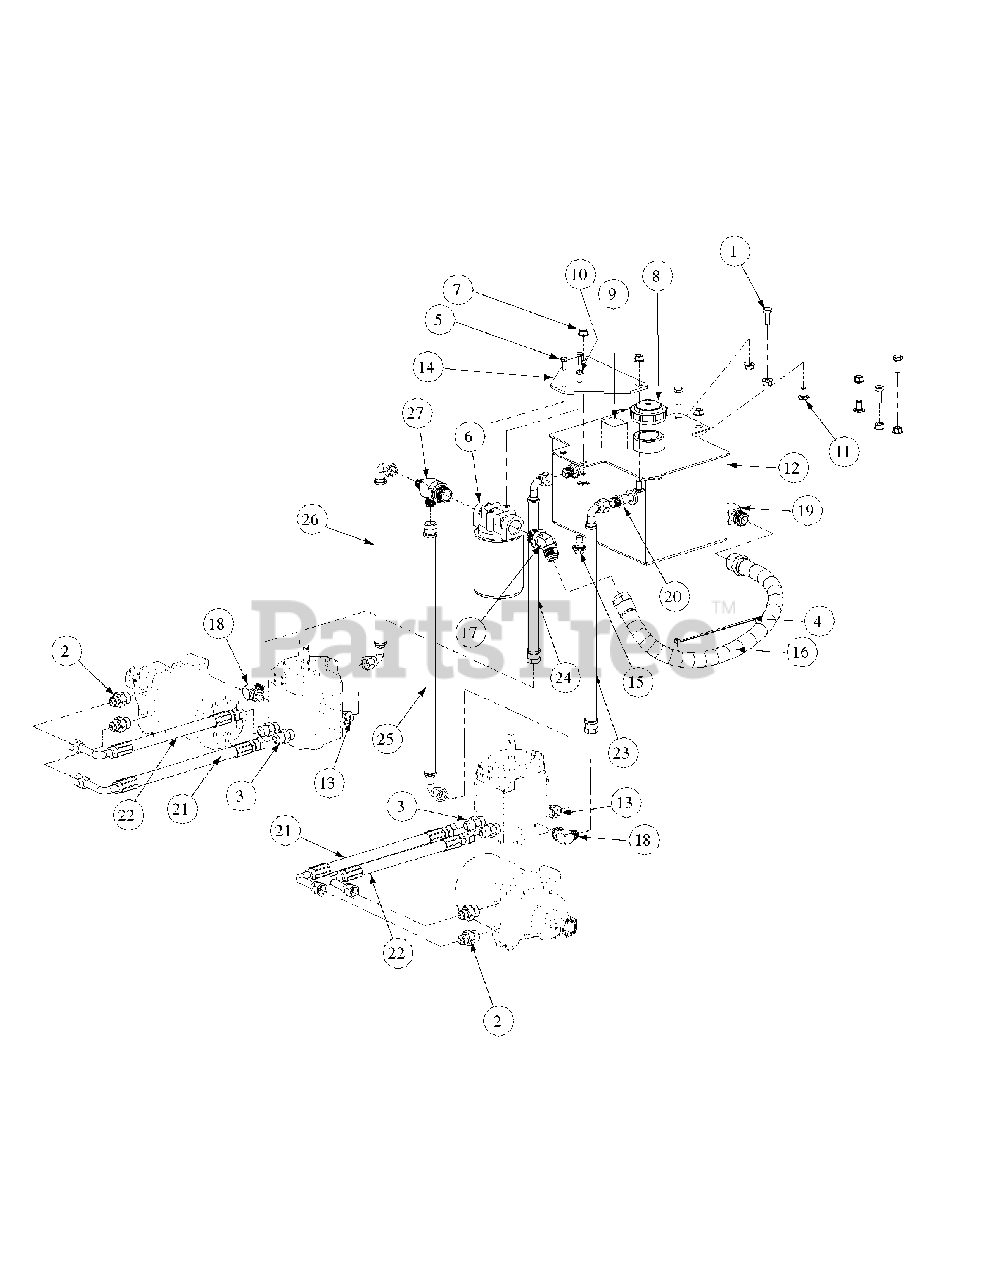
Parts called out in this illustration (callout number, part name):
1	Hex Cap Screw, 3/8-16, 1
2	Fitting 1/2 x 3/4 - O Ring
3	Fitting 1/2 x 3/4 - O Ring to Flare
4	Cable Tie, 3/16 x .05 x 7.4
5	Hex Cap Screw, 1/4-20, .75
6	Filter Head 3/4
7	Hex Nut Flange Lock, 3/8-16
8	Cap, Hydro Oil Tank
9	Decal Oil Only 20W50
10	Lock Washer, 1/4
11	Carriage Bolt, 3/8-16 x .75 LG.
12	Hydraulic Tank Assembly
13	Fitting Connector, 1/2 x 3/8
14	Oil Filter Mounting Plate
15	Oil Pan Drain w/ Seal and Plug
16	Tank to Filter Hose Assembly
17	Connector, 3/4 x3/4
18	Elbow Fitting, 3/8 O-ring, 1/2 Flare
19	Fitting Elbow, 1/2 x 1/2
20	Fitting, 3/8 NPT, 1/2 Flare
21	Long Pressure Hose Assembly
22	Short Pressure Hose Assembly
23	17.75" Return Hose Assembly, RH
24	14" Return Hose Assembly, LH
25	21.25" Supply Hose Assembly, RH
26	15.50" Supply Hose Assembly, LH
27	Tee Fitting, 3/4 x 1/2 x 1/2
